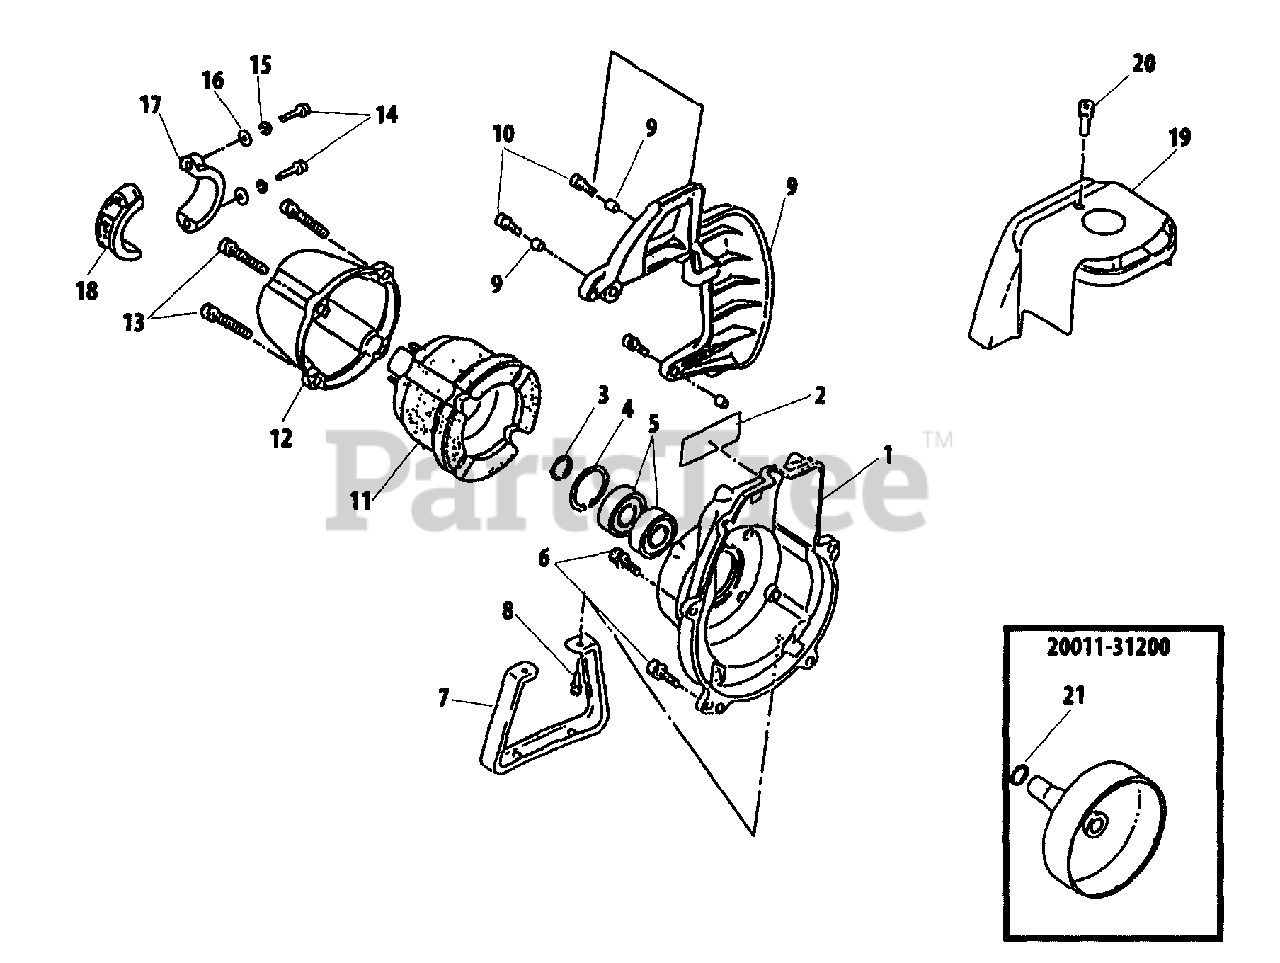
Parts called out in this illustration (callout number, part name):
1	CASE, FAN
2	LABEL - MODEL
3	RING, RETAINING
4	RING, RETAINING - 32
5	BEARING, BALL - 6002
6	SCREW - 5X20
7	STAND
8	SCREW - 5X16
9	PROTECTOR ASSY
10	SCREW - 4X16
11	CUSHION
12	CONNECTOR, CAP
13	SCREW - 5X20
14	SCREW - 5X25
15	LOCKWASHER - 5
16	WASHER - 5
17	CLAMP - B
18	CLAMP - A
19	COVER, ENGINE
20	SCREW - 5X14
21	RING, RETAINING
20011-31200	DRUM, CLUTCH
